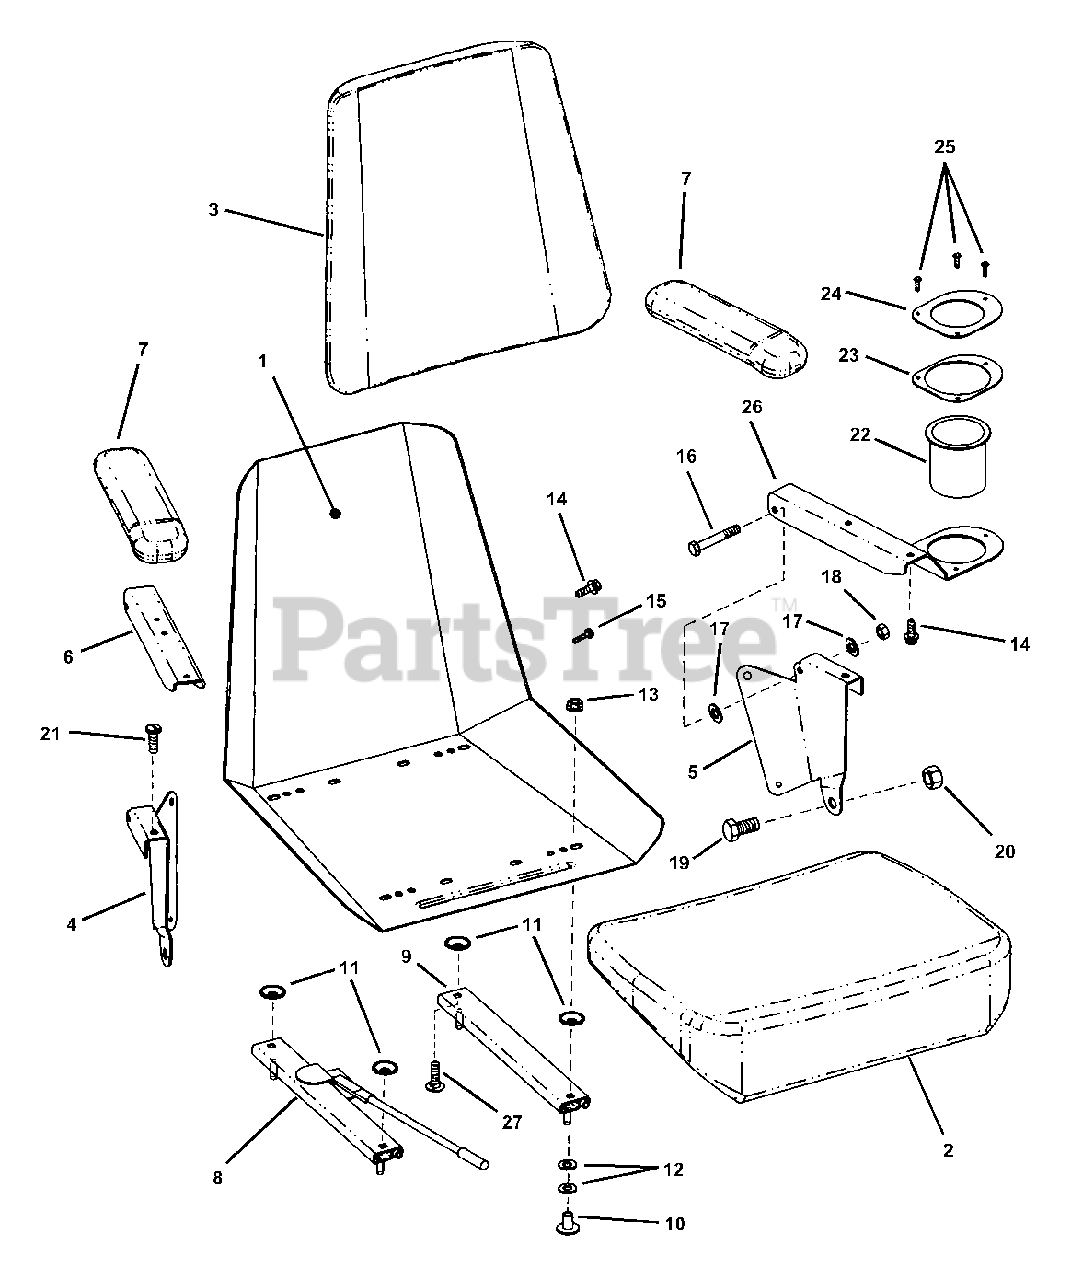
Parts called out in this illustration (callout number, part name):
1	PAN, Complete
2	CUSHION, Seat
3	CUSHION, Back
4	BRACKET, Armrest (Right Hand
5	BRACKET, Armrest (Left Hand)
6	CHANNEL, Armrest
7	ARM PAD, Grey
8	ADJUSTER (with lock)
9	ADJUSTER (without lock)
10	STUD GUARD
11	SPACER, Bell
12	WASHER, 5/16" Flat
13	NUT, 5/16-18 Hex Flange Lock, Grade 5
14	SCREW, 1/4-20 x 3/4" Phillips
15	SCREW, #8-32 x 1/2" Self Tapping
16	BOLT, 5/16-18 X 2", GD5
17	WASHER, 13/32" I.D. x 3/4 O.D. Poly
18	NUT, 5/16-18 Hex Head Center Lock, Grade B
19	SCREW, 1/2-13 x 1" Hex Head Cap, Grade 5
20	NUT, 1/2-13 Hex Head Center Lock, Grade 5
21	SCREW, 5/16-18 x 1" Slotted Pan Head
22	HOLDER, Beverage
23	SPACER, Cup Holder
24	COVER, Cup Holder
25	RIVET, 3/16" Pan Head
26	BRACKET, Armrest Cup Holder
27	BOLT, 5/16-18 x 1" Short Neck Carriage, Grade 5
